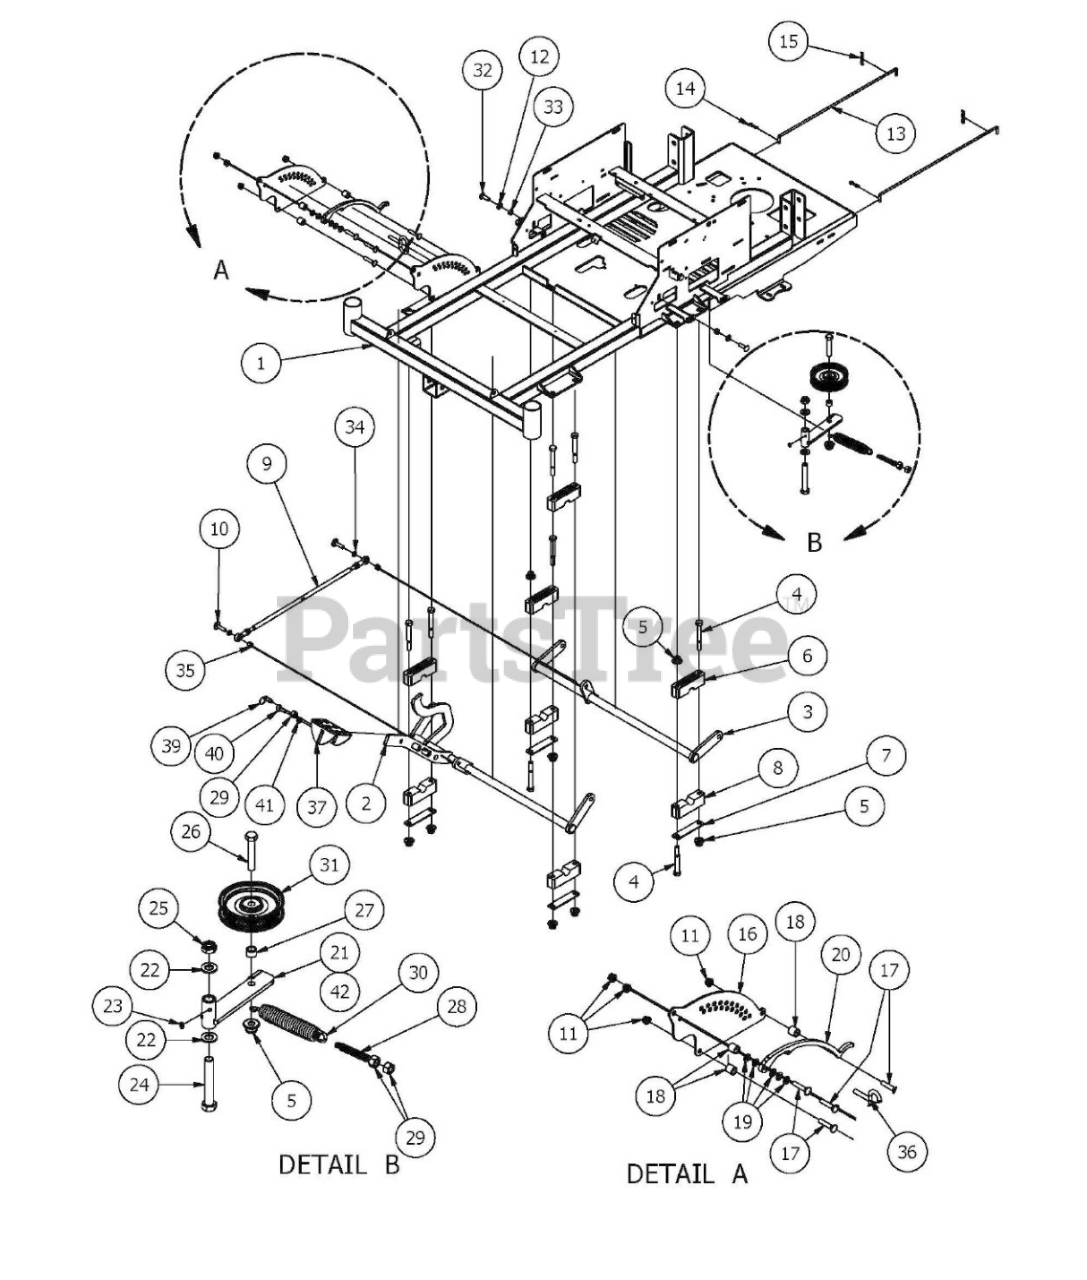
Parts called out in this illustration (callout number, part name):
1	2017 Compact Outlaw Frame
2	Actuator Bar Front- 2016 Compact Outlaw
3	Actuator Bar Rear- 2016 Compact Outlaw
4	1/2" x 4" Bolt (Grade 8)
5	1/2-13 Nylon Flange Nut
6	Two Piece Pillow Block (Male)
7	Two Piece Pillow Block Strap
8	Two Piece Pillow Block (Female)
9	Actuator Bar Linkage Assembly
10	3/8 x 1-1/2 Carriage Bolt
11	3/8" Nylock Flange Nut
12	3/8" Flat Washer
13	ZT Neutral level rod 2011
15	Neutral Rod Clip
16	Outlaw Height Indicator Plate (Outer)
17	3/8 x 1 3/4 Carriage Bolt
18	3/4 OD x 1/2 ID x 3\4 Length
19	.390 x .750 x .062 Nylon Washer
20	Outlaw Deck Lever Lock
21	Pump Idler Bracket
22	.630 ID Plastic Washer
23	1/4" Press in Grease Fitting
24	5/8" x 4" Hex Bolt
25	5/8" Nylock (1/2 Jam)
26	1/2" x 2 3/4" Hex Bolt
27	1/2 x 1/2 Spacer
28	All Thread-Pump Idler Tensioner
29	1/2" Hex Nut
30	2015 Deck Idler Spring
31	4 3/4" Idler Pulley
32	3/8" x 1 1/4" Carriage Bolt
33	3/8" Hex Nut
34	3/8" Lock Washer
35	3/8 Nylock Nut
36	Deck height lever pin
37	Outlaw Deck Lift Pedal
38	Pedal Tab (Foot Assist)
40	5/16-18 x1 Thumb Screw Zinc
41	5/16" Flange Nut
42	Pump Idler Assembly (Parts 5,21,23,26,27,31)
